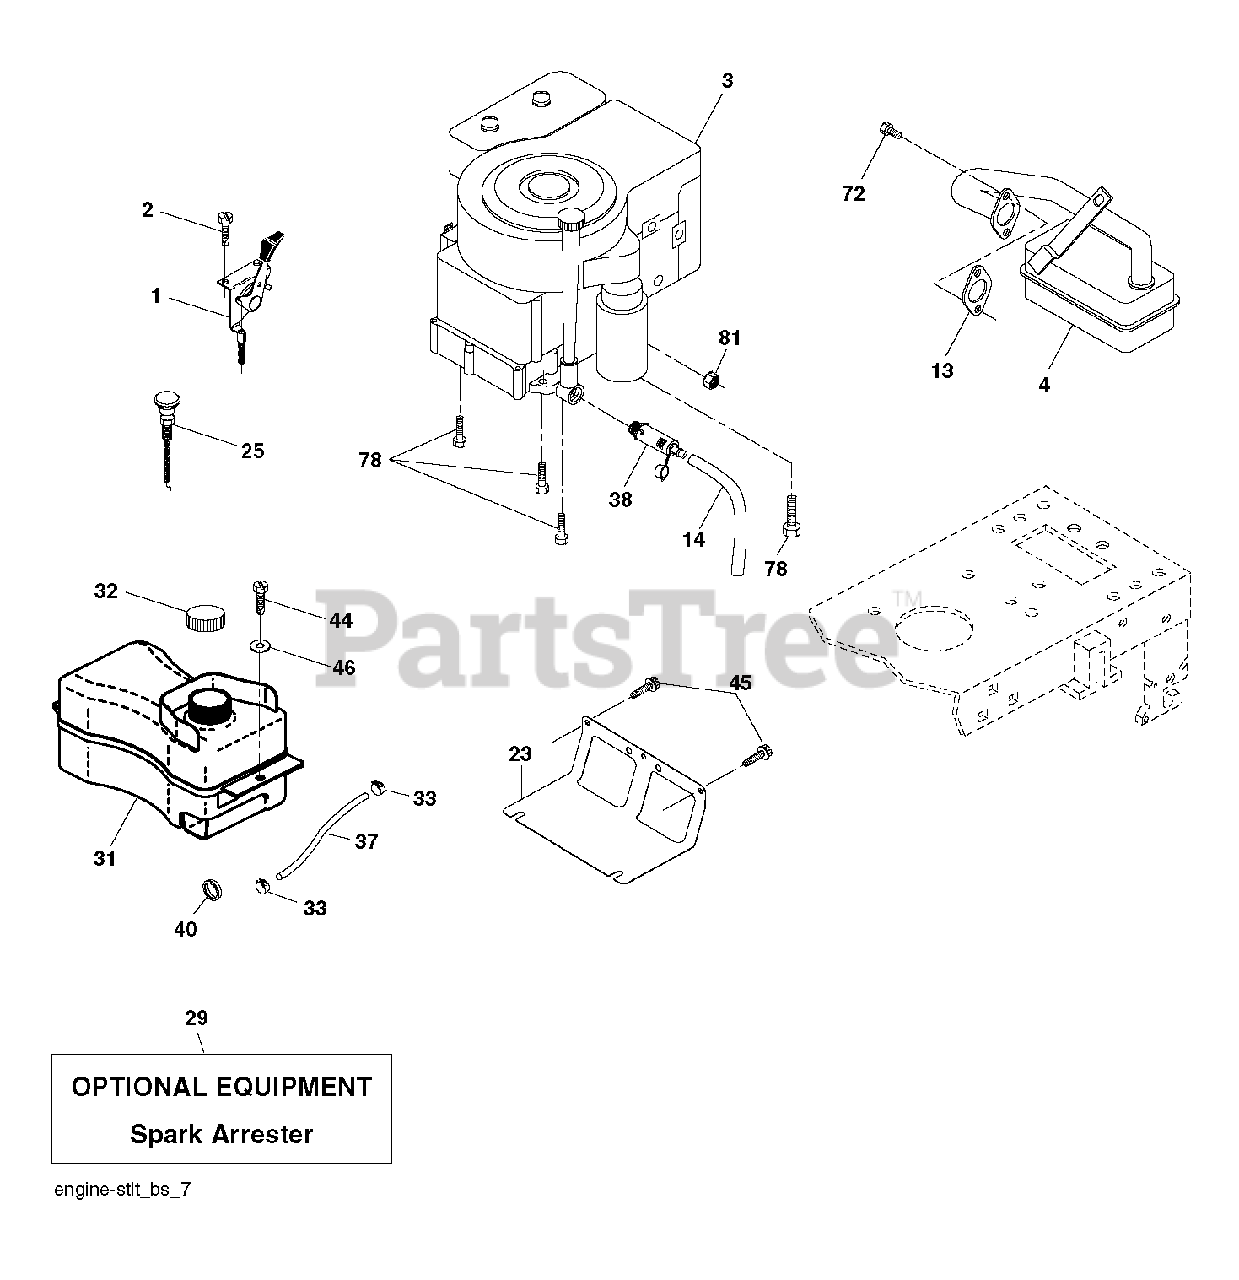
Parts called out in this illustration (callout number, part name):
1	CONTROL TH/CH FLAG
2	SCREW
13	REPL BY 532 27 22-93
14	TUBE, DRAIN OIL ASM.
23	SHEILD.BROWNING.DBR.GUARD
29	ARRESTER SPARK (OPTIONAL)
32	CAP.FUEL.2.25"VENTED"
33	HOSE CLAMP
37	LINE.FUEL.20
38	VALUE.OIL.DRAIN
40	GROMMET T
44	SCREW HEXWSHR 1/4-20X3/4
45	SCREW, 3/8-16X3/4
72	SCREW.SOCKET HD.5/16-1
78	SCREW.3/8-16
81	NUT
